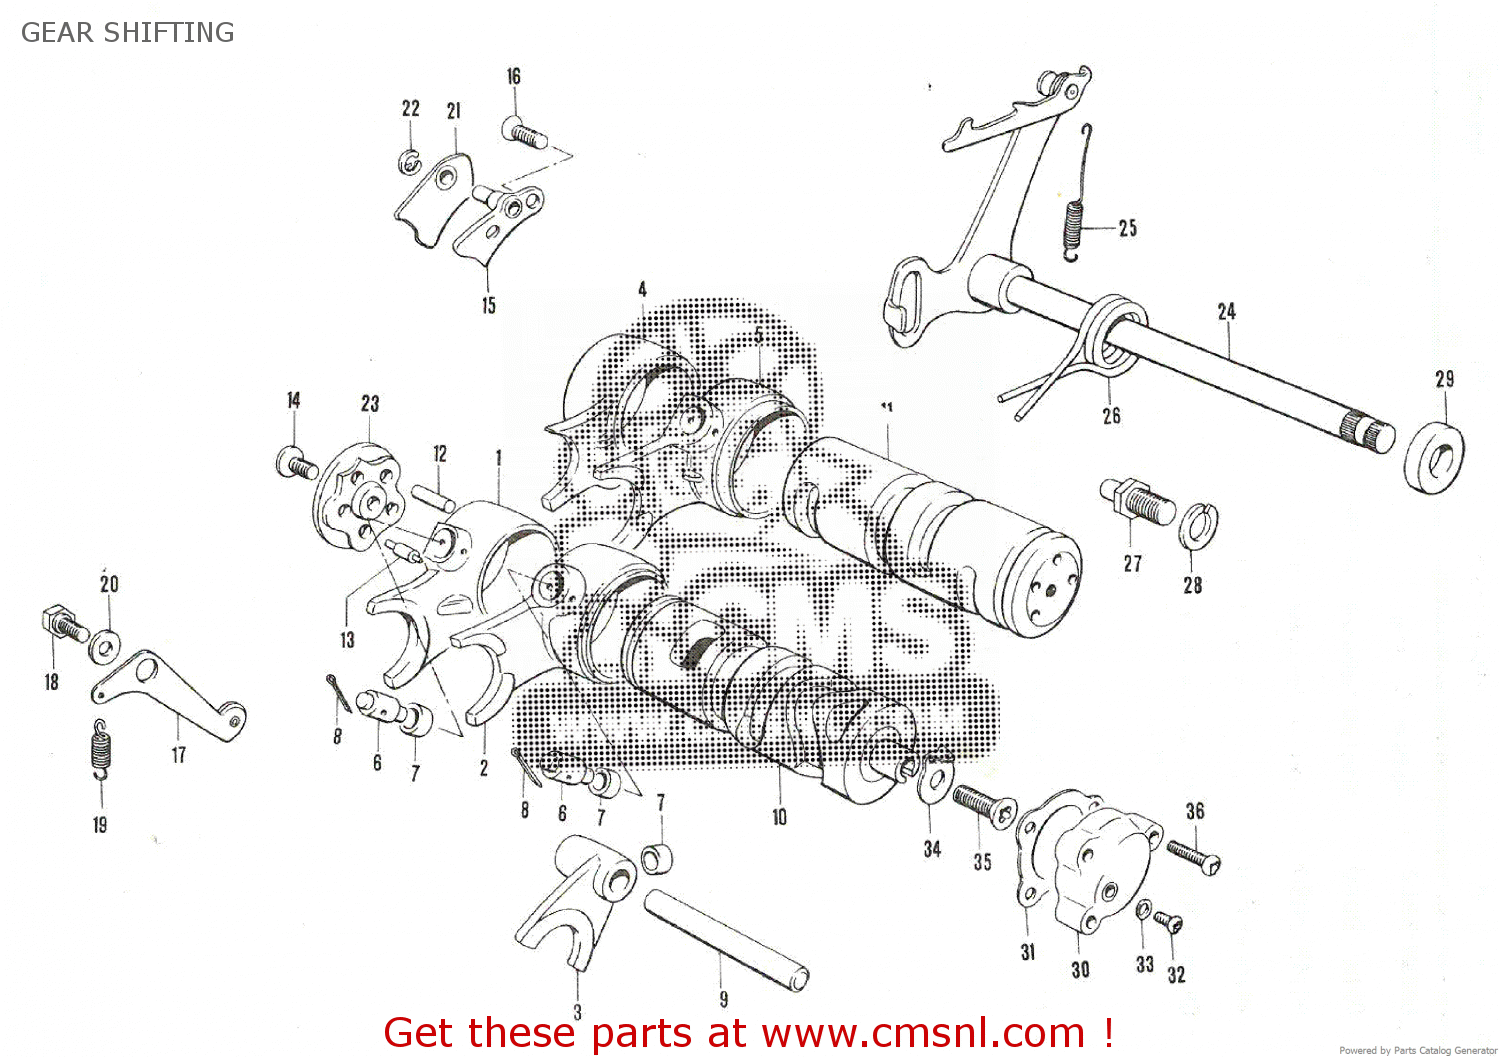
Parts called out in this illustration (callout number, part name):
1	FORK,GEAR SHIFT NO.1
2	FORK,GEAR SHIFT NO.2
3	FORK,GEAR SHIFT NO.3
6	PIN
7	SPACER
8	PIN 25X20
9	SHAFT,GEAR SHIFT FORK
10	CAM,GEAR SHIFT
12	PIN(4X20)
13	PIN
14	CROSS HEAD SCREW
15	GUIDE,GEAR SHIFT CAM
16	SCREW
17	STOPPER,GEAR SHIFTING
18	BOLT(6X16.1)
19	SPRING
20	WASHER(6.5X16X2.3)
21	PAWL,GEAR SHIFTING CAM
22	E RING
23	PLATE,GEAR SHIFT CAM STOPPER
24	SHAFT,GEAR SHIFT
25	SPRING
26	SPRING
27	STOPPER,GEAR SHIFT ARM
28	LOCK WASHER
29	OIL SEAL
30	SWITCH,NEUTRAL INDICATOR
31	GASKET,GEAR SHIFT SWITCH (NAS)
32	CROSS HEAD SCREW
33	WASHER
34	POINT,NEUTRAL INDICATOR SWITCH CON
35	SCREW
36	SCREW
